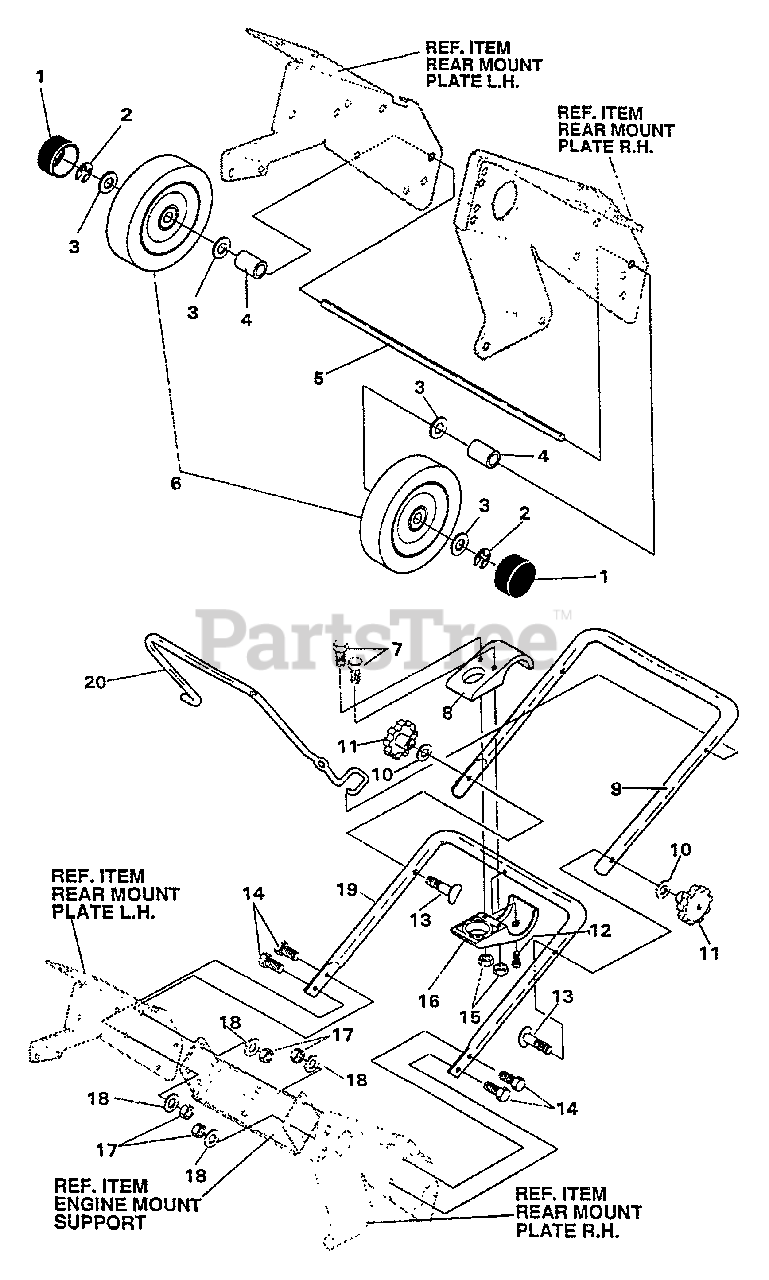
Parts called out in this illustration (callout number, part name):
1	CAP, HUB
2	RING, RETAINING
3	WASHER
4	SPACER
5	SHAFT, AXLE 5/21
6	WHEEL ASSY
7	SCREW #10-24×1.00
8	BRKT HALF, CHUTE CRANK
9	HANDLE, UPPER
10	WASHER
12	SCREW 1/4"-20×0.63
13	BOLT, 5/16-18×2.00
14	SCREW 5/16"-18×0.75
15	NUT
16	BRKT HALF, CHUTE CRANK
17	NUT, 5/16"-18
18	WASHER
19	HANDLE, LOWER
20	BAR, CONTROL DRIVE 0.31 DIA.
